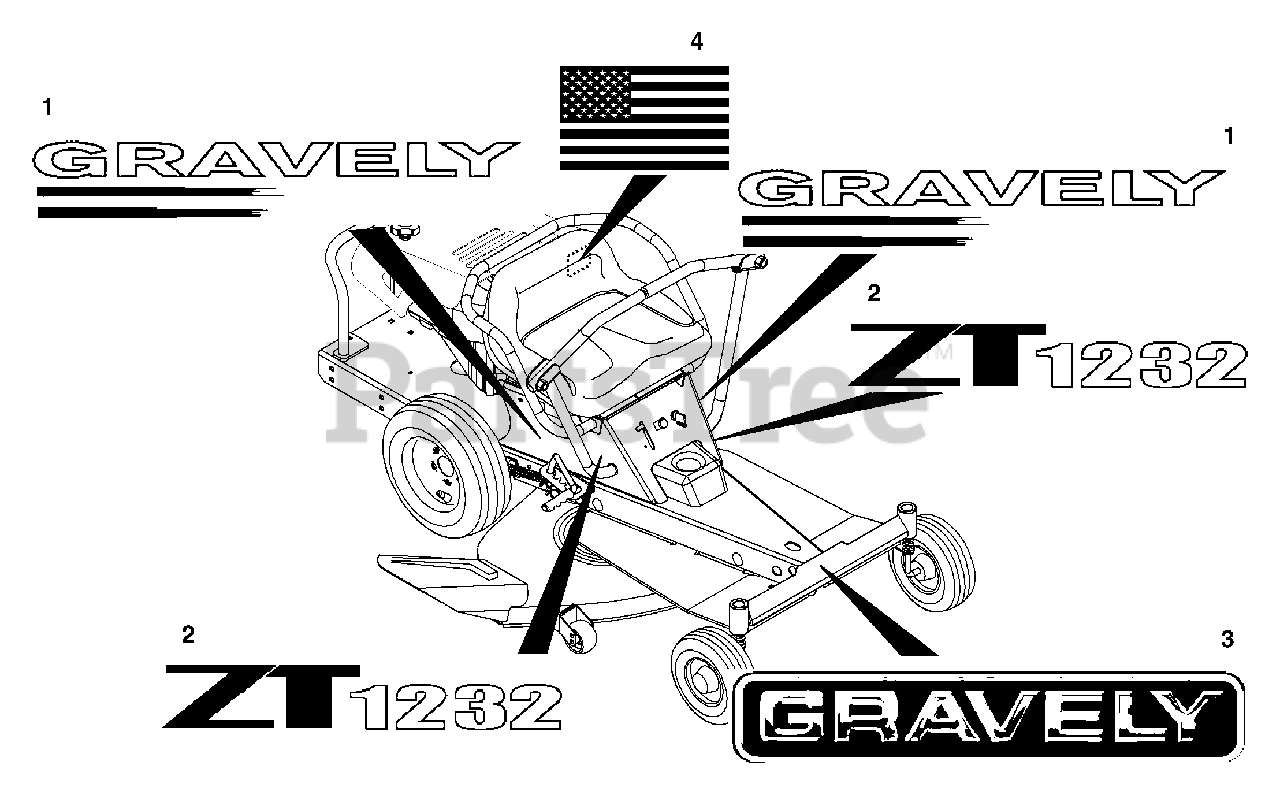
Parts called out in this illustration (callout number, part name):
1	Decal, Gravely ZT
2	Decal, Gravely 1232 (030)
2	Decal, Gravely 1440 (032)
3	Decal, Gravely
4	Decal, American Flag
